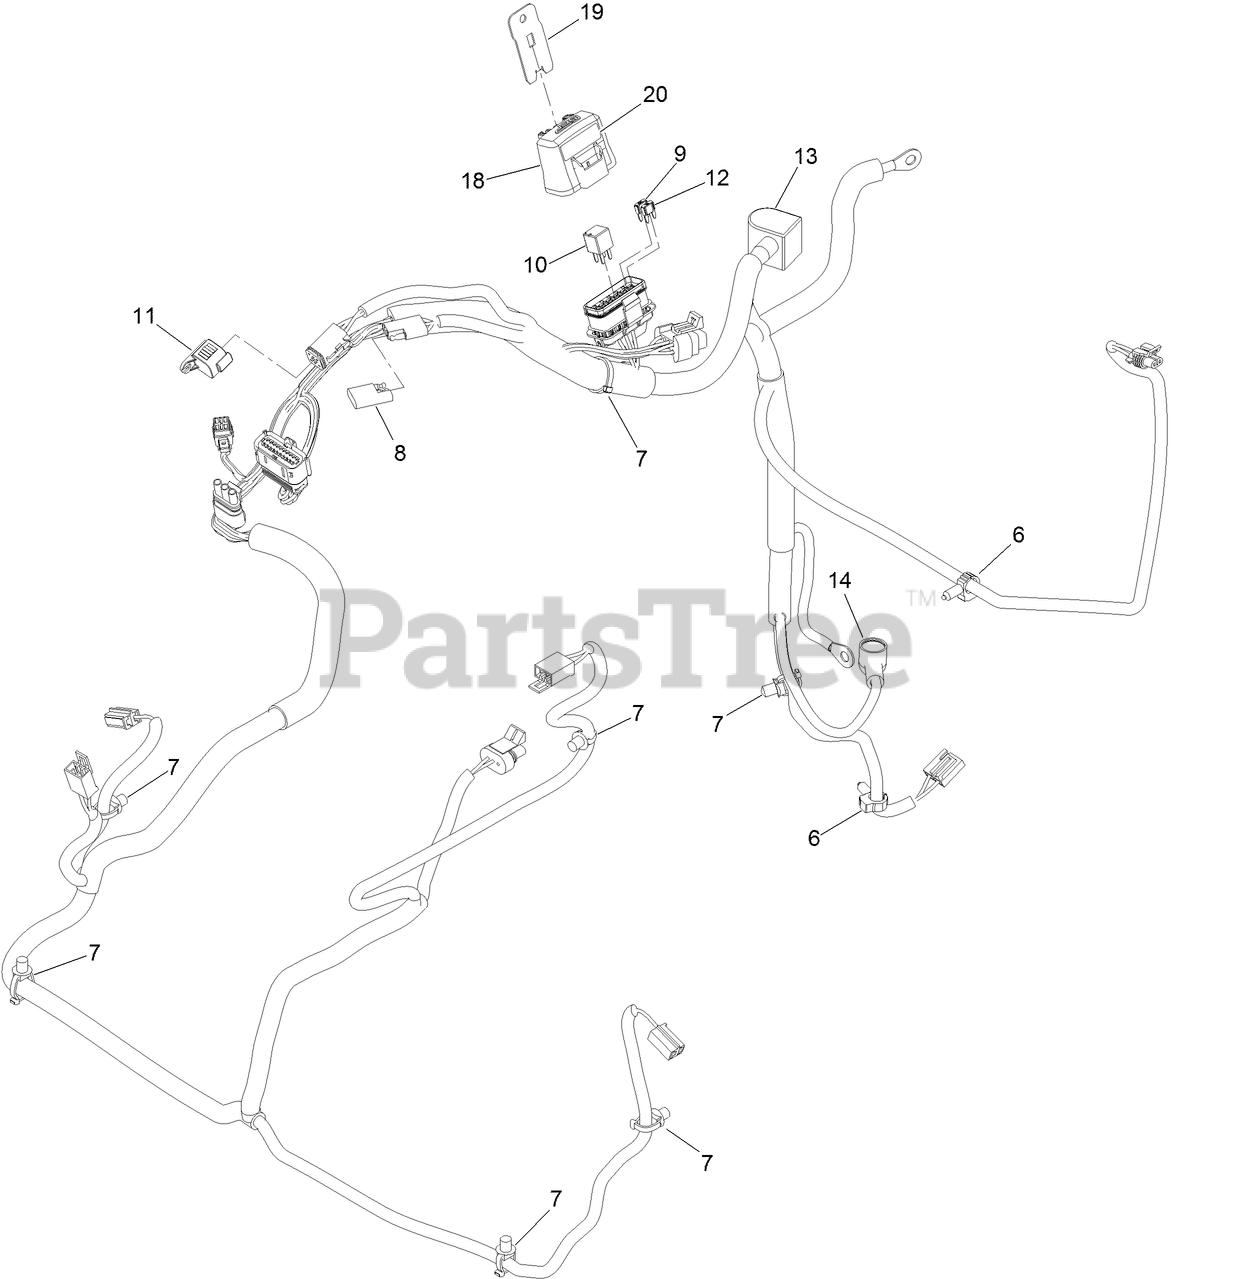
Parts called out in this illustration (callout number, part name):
6	CLIP-HARNESS
7	CLIP-TIE
8	CAP-PLUG
9	FUSE-MINI BLADE, 20 AMP
10	RELAY-MICRO
11	CAP-PLUG, 6 WAY
12	FUSE-MINI BLADE, 15 AMP
13	INSULATOR-BATTERY
14	INSULATOR-SOLENOID
18	COVER-BLOCK, FUSE
19	CLIP-MOUNTING
20	DECAL-FUSE
